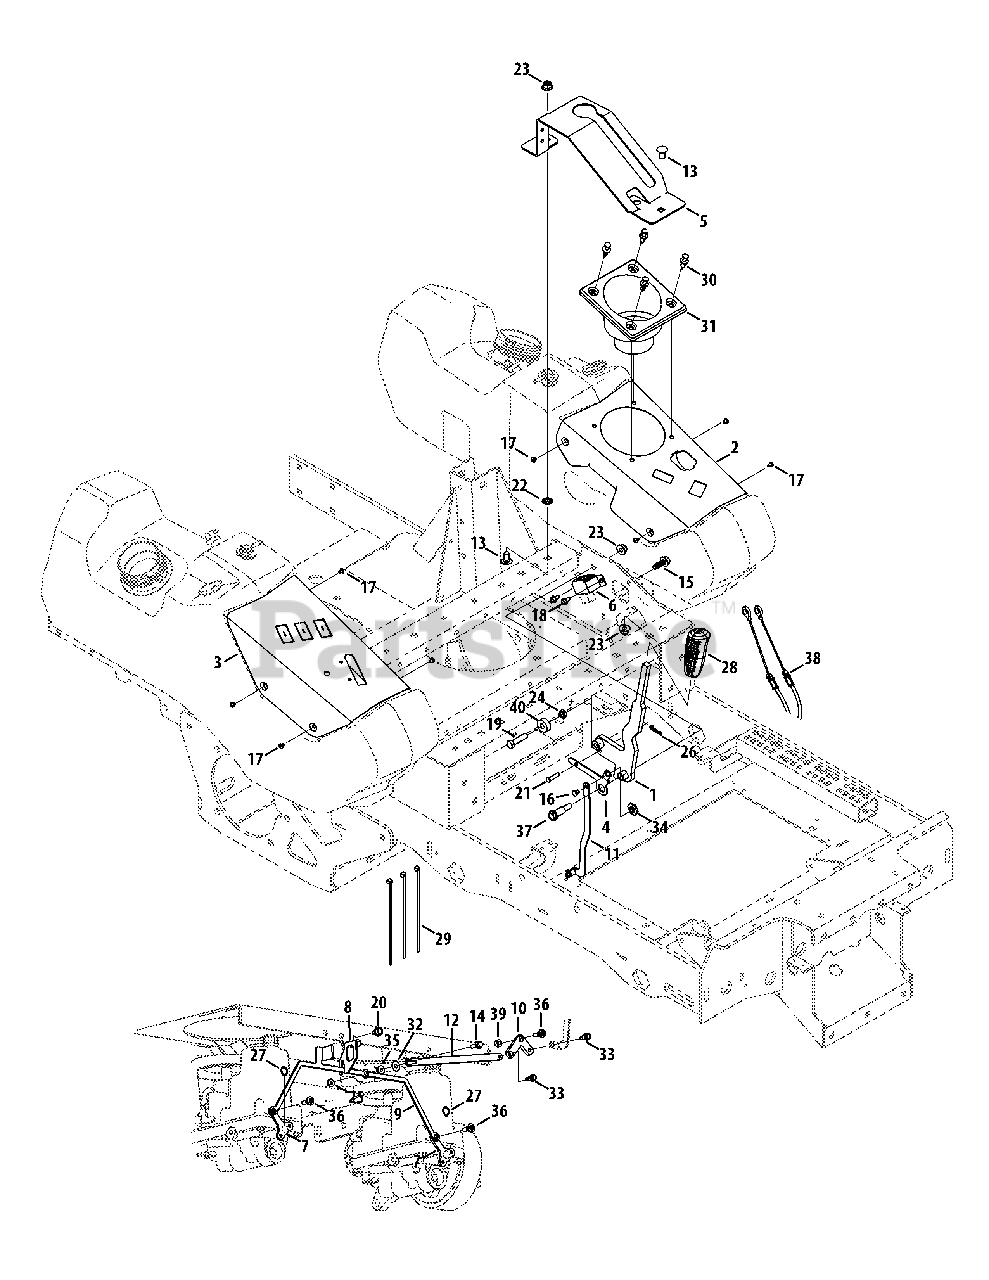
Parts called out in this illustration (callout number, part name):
1	Brake Handle Assembly
2	LH Control Panel
3	RH Control Panel
4	Dump Valve Release Lever
5	Boot Brake Bracket
6	Brake Switch Mount
7	Transmission Bypass Lever
8	Neutral Switch Bracket
9	Dump Valve Actuator Bracket
10	Neutral Pivot Control Lever
11	Neutral Arm
12	Transmission Link Arm
13	Carriage Bolt, 3/8-16 x .75
14	Hex Flange Screw, 1/4-20 x .75
15	Screw, 3/8-16 x 1.00
16	Screw, M6 x 8mm
17	Machine Screw, #10-32 x .25
18	Hex Flange Screw, 1/4-20 x .500
19	Hex Cap Screw, 3/8-16 x 1.50
20	Screw, 5/16-18 x .50
21	Clevis Pin, .25 x 1.00
22	Push Nut, 3/8
23	Nut, 3/8-16, Flangelock
24	Jam Nut, 3/8-16
25	Nut, 1/4-20, Hexflange
27	Retainer Ring
28	Grip, .50 ID
29	Cable Tie
30	Rivet, .3125
31	Cup Holder
32	Flat Washer, .283 x .750 x .030
33	Shoulder Screw, .342 x .335, 1/4-28
34	Shoulder Spacer, M6
35	Shoulder Spacer, .375 x .625 x .20
36	Shoulder Screw, .375 x .280, 1/4-14
37	Shoulder Bolt, .50 x .925, 3/8-16
38	Brake Cable
39	Spacer, .256 x .500 x .240
40	Spacer, .406 x 1.00 x .38
